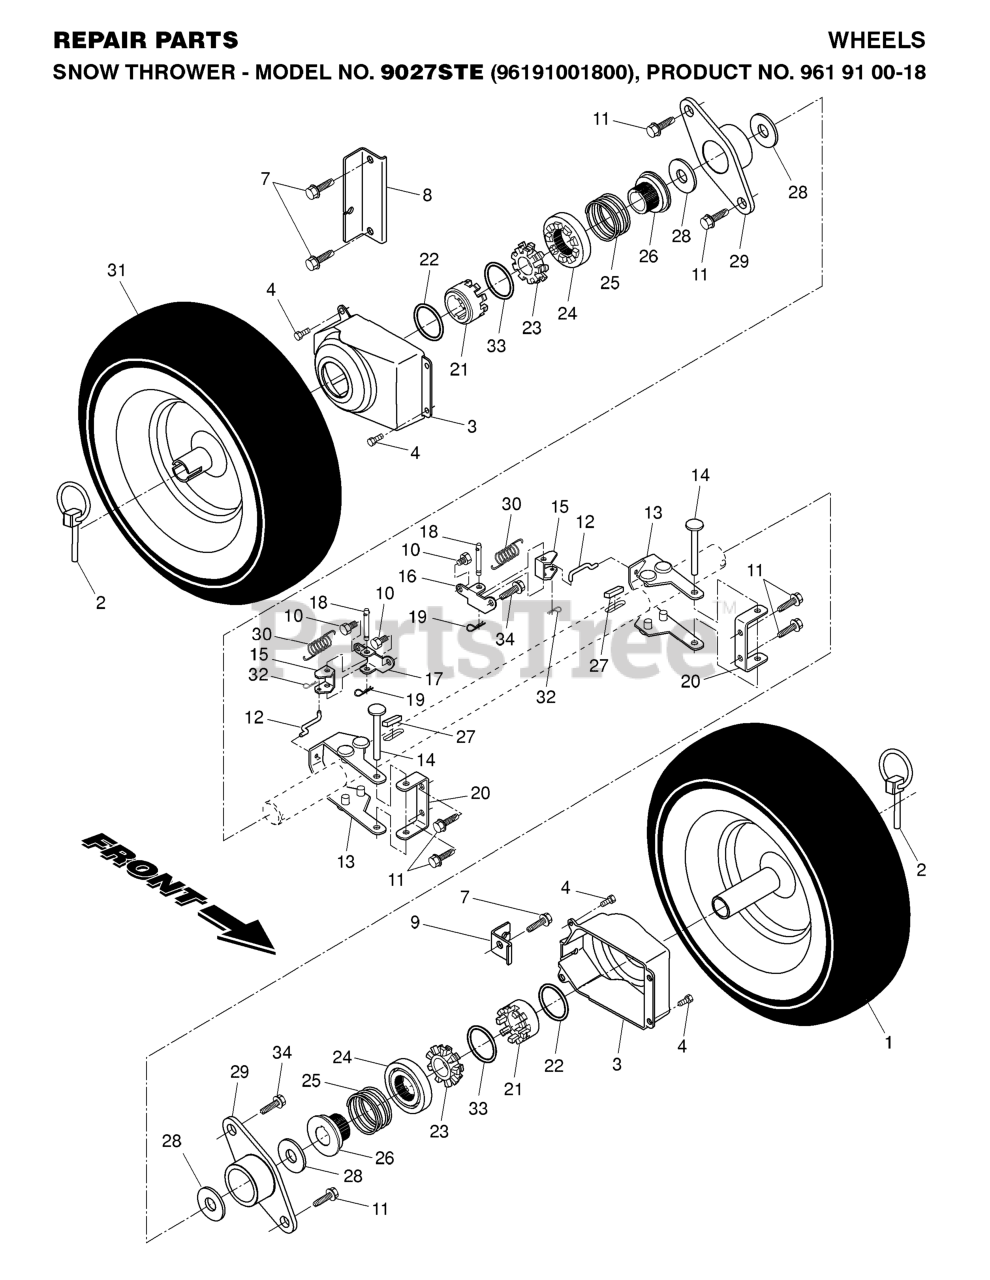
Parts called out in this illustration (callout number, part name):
1	16 X 4.8 LH WHEEL GREY
2	PIN KLIK, 1/4
3	COVER, POWER STEERING
4	SCREW, HEX HEAD, TAPPING
7	SCREW 3/8-16X1
8	BRACKET, STEERING CABLE RH
9	BRACKET, STEERING CABLE LH
10	SCREW 1/4X20
11	Screw 5/16-18 x 1/2 Hex, Self Tapping 5/16-18 x 1/2
12	LINK.STEER.YOKE
13	YOKE, STEERING
14	PIN, STEERING LEVER
15	BELLCRANK.STEER
16	BRACKET.STEER.PIVOT.LH.YZ
17	BRKT.STEER.PIVOT.RH
18	PIN, STEERING BELLCRANK
19	RETAINER CLIP PM
20	BRACKET.STEER.PNT.BLACK
21	RP.DRIVER WHEEL
22	RING, WIRE RETAINER
23	LOBE WHEEL
24	RP.SLIDE.CLUTCH
25	SPRING, CLUTCH SLIDE
26	RP.LOBE.AXLE
27	KEY, SQUARE 1/4 X .875
28	WASHER TRUST 1"
29	BEARING, AXLE
30	SPRING LATCH
31	16 X 4.8 RH WHEEL
32	RETAINER CLIP
